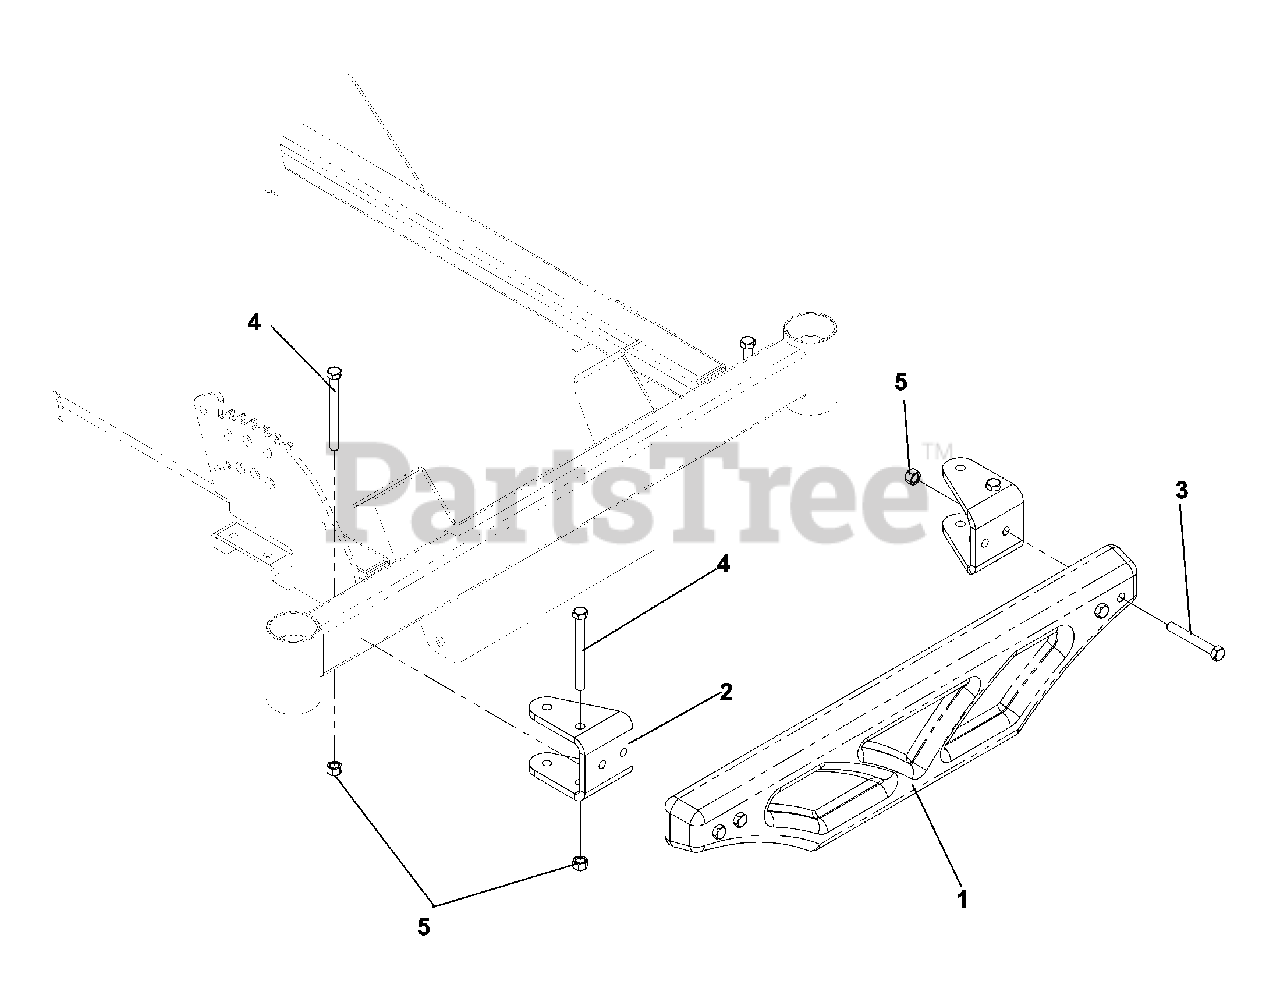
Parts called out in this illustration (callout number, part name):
1	CAST WEIGHT
2	BRACKET, WEIGHT
3	HEX SCREW 3/8-20 X 2.75
4	HCS3/8-16.X
5	NUT 3/8-16 NYLOC
